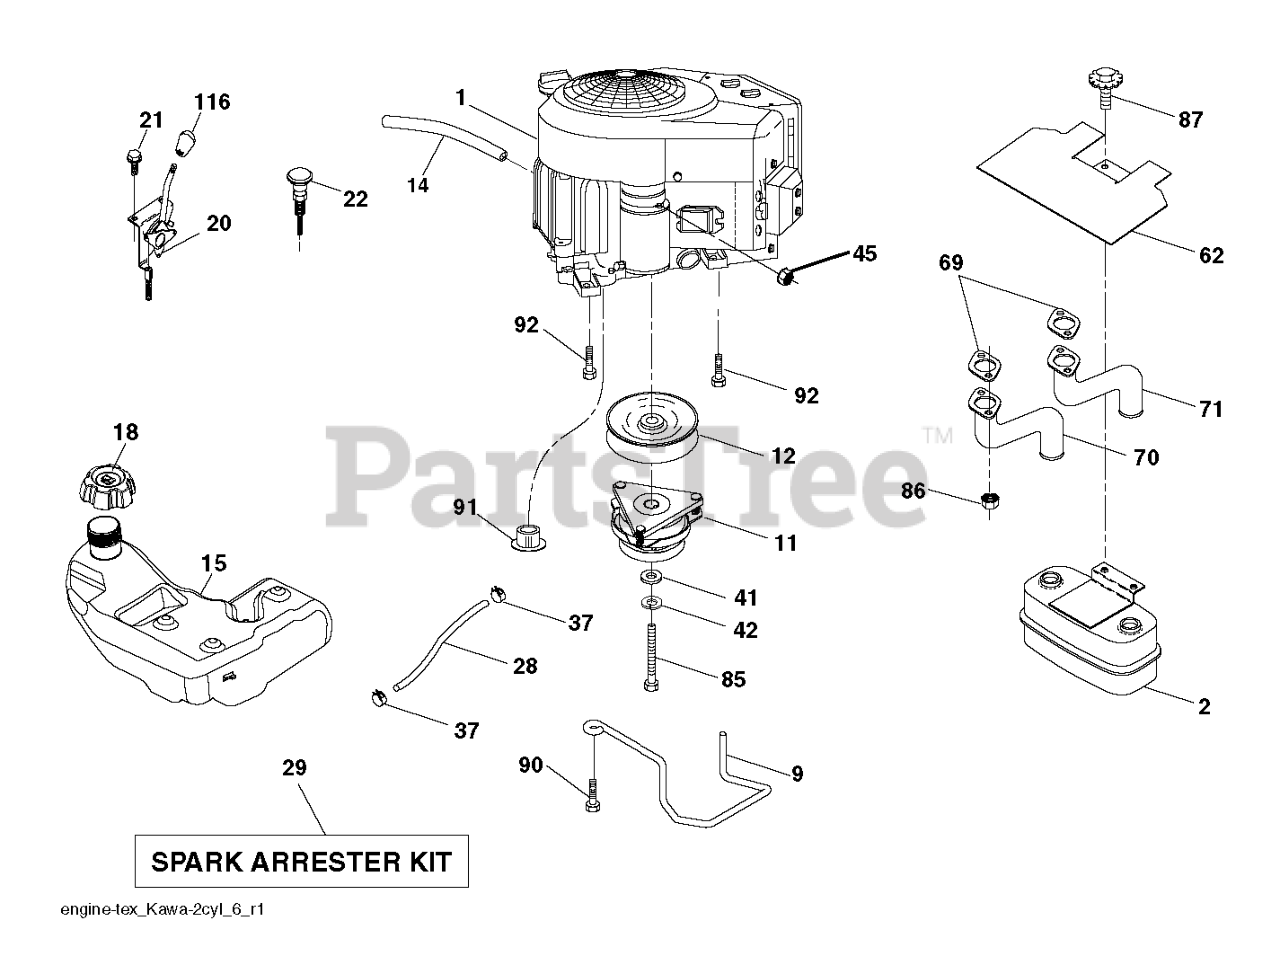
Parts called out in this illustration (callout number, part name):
2	MUFFLER.TWIN.CYL.LOW.TONE
9	KEEPER.BELT.ENGINE.4.2
11	CLUTCH.ELECTRIC.LT.48"*
12	PULLEY.ENGINE.TUFFTORQ
14	TUBE, DRAIN OIL ASM.
15	RP_TANK.ASSY.3.GAL.EPA
18	CAP.ASM.FL.RITCH.3"E10.SYM.498
20	CONTROL.THROTTLE.PRO.
21	SCREW.#10 X 0.750.BOS
22	CONTROL.CHOKE.ERGO.PUSH-IN.BLA
28	REPL BY 532 00 85-43
29	KIT.SPARK ARRESTOR 794945 B&S
37	HOSE CLAMP
42	LOCKWASHER
45	NUT
62	SHIELD.HEAT.MUFFLER
70	TUBE.EXHAUST.LH.FR961/FR730
71	TUBE.EXHAUST.RH.FR961/FR730
85	BOLT HEX 7/16-20X4-1/4"
86	NUT.HEX.FLANGE.TOPLOCK
87	BOLT 5/1618UNC X 3/4 W/ SEMS
90	SCREW 3/8-16X1
91	BUSHING.1.375OD
92	SCREW 3/8-16X1
116	KNOB - SHIFT
